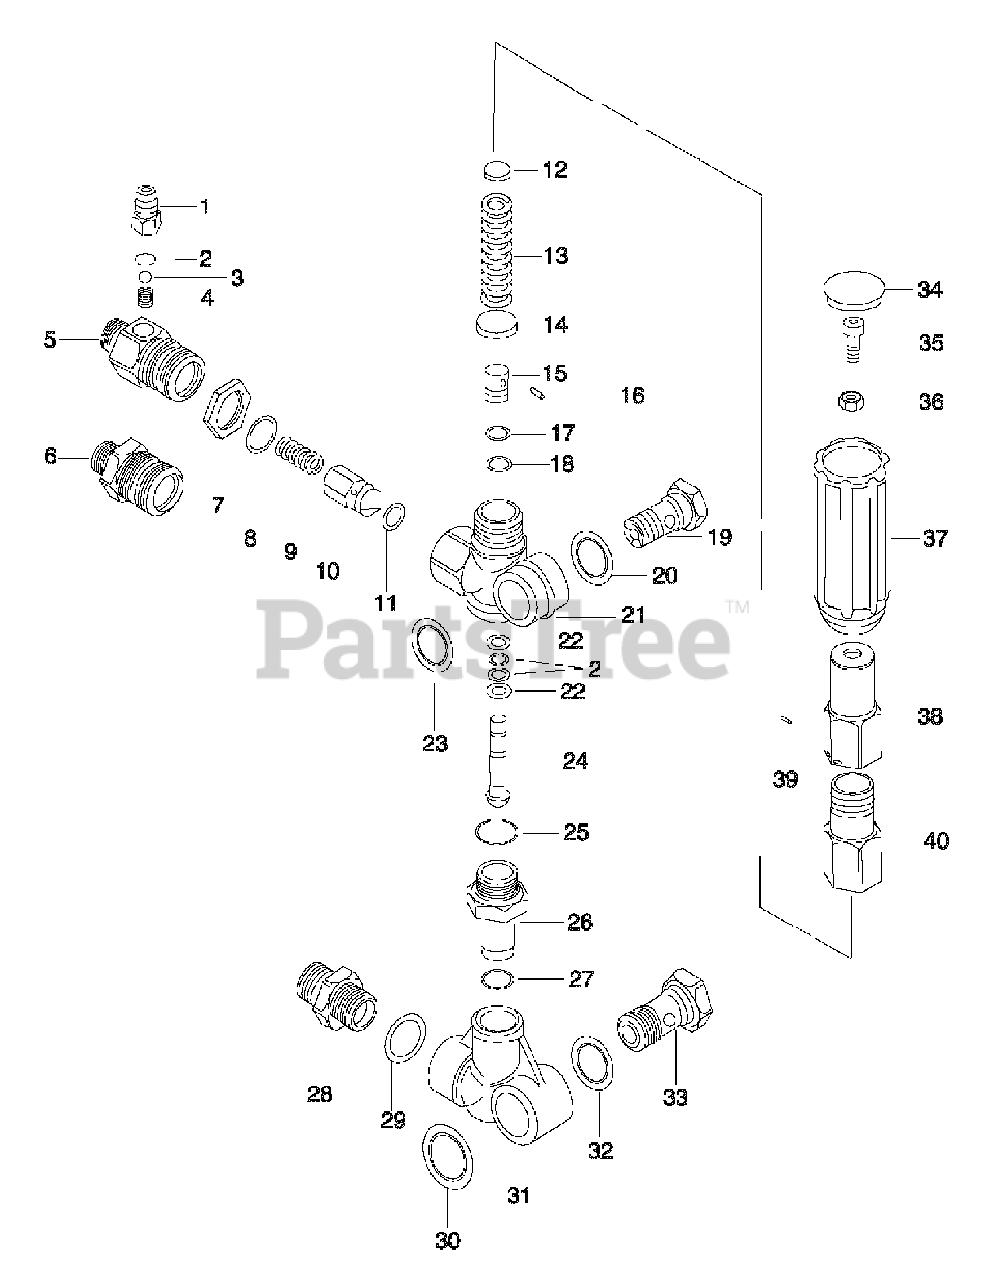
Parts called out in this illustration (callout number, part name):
1	Hose Tail
2	O-Ring
3	Stainless Ball
5	Injector Body
7	Injector Nut
12	Spacer Plate
14	Spring, Spacer Plate
15	Upper Piston
19	Inlet Bolt
21	Valve Housing
24	Lower Piston
26	Piston Guide
28	Suction Fitting
31	Bypass Fitting
33	Inlet Bolt
40	Spring Guide
